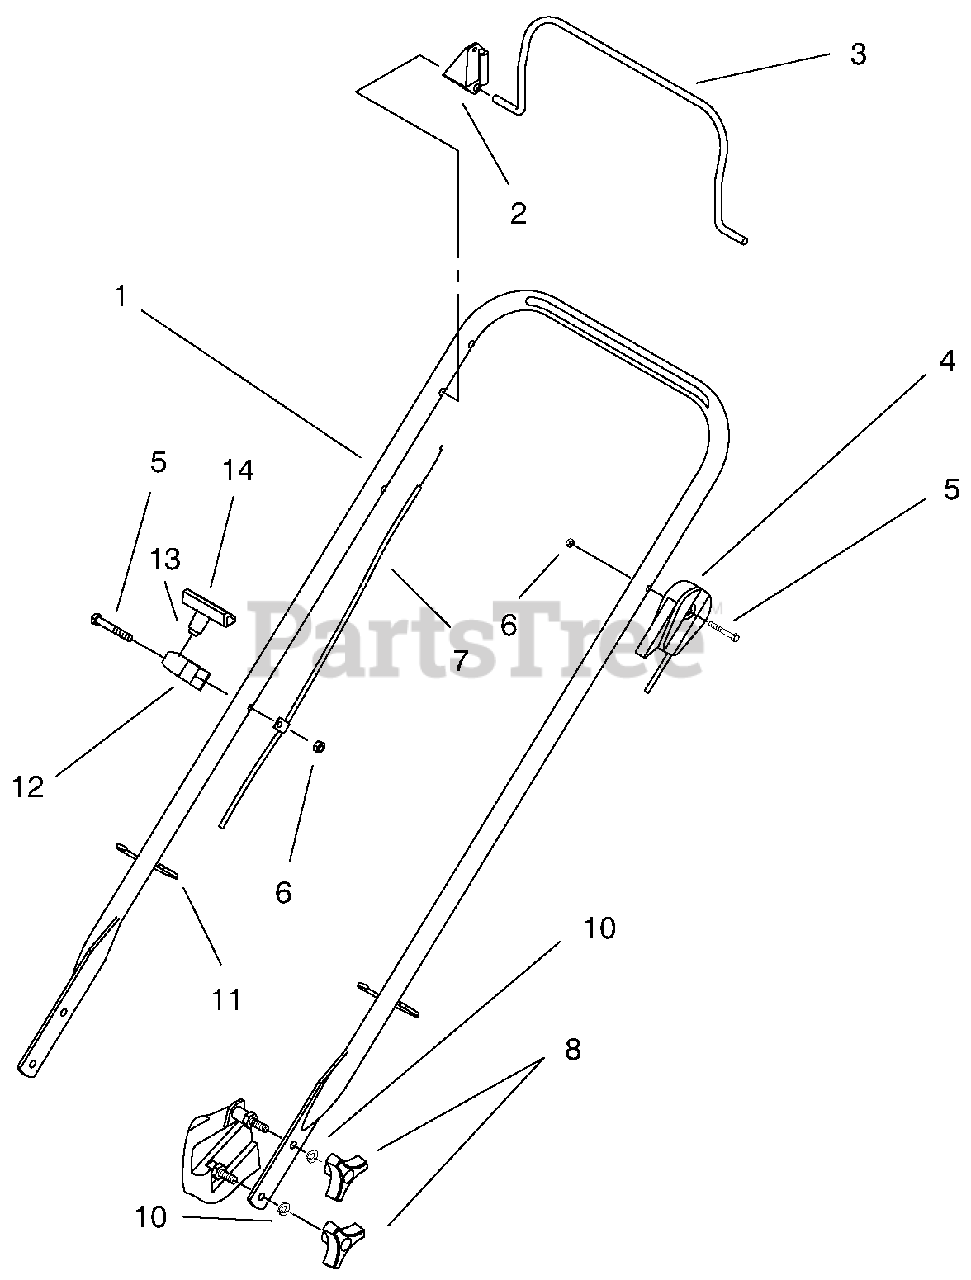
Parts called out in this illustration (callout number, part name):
2	STOP-PIVOT
3	Bail-Brake
4	CABLE - THROTTLE
5	SCREW-HH
6	NUT-LOCK, NI
7	CABLE - BRAKE
8	HANDLE-KNOB
10	WASHER-LOCK
11	TIE-CABLE
12	GUIDE-ROPE
13	HANDLE-START
14	CLIP-STARTER
